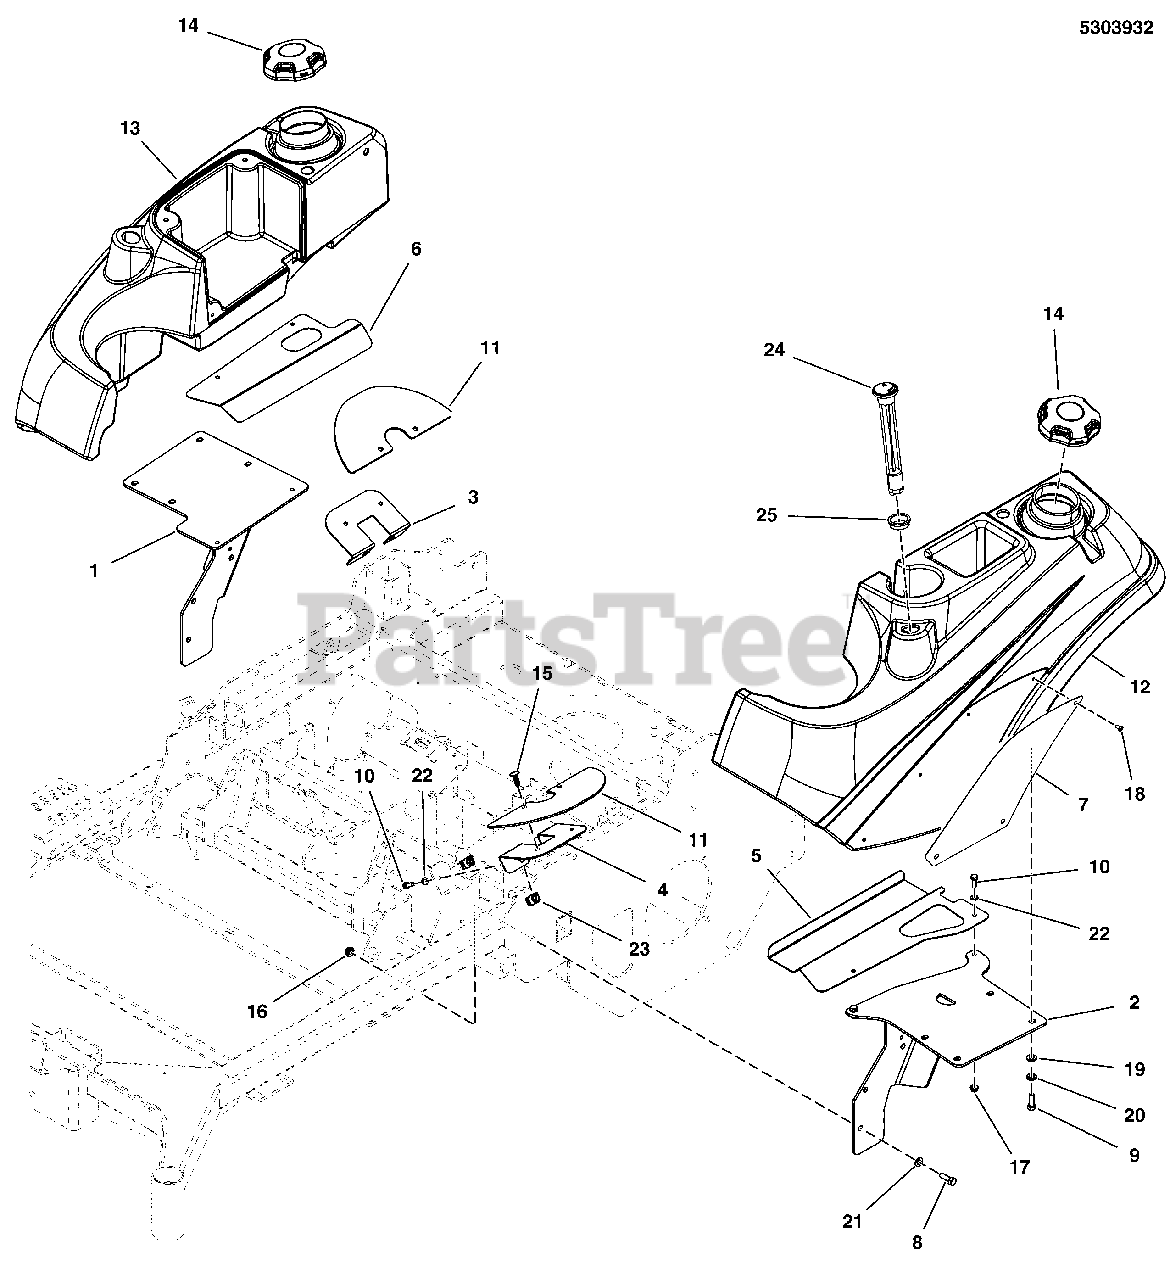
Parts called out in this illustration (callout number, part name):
1	WELD, FUEL MOUNT, RH, MASSEY 3900 - BLK
2	WELD, FUEL MOUNT, LH, MASSEY 3900 - BLK
3	GUARD,MOTION CONTROLS,RH,MASSEY 3900-BLK
4	GUARD,MOTION CONTROLS,LH,MASSEY 3900-BLK
5	GUARD, SEAT, LH - BLK
6	GUARD, SEAT, RH - BLK
7	PLATE, TANK BADGE - IS2000/COBALT - RED
8	BOLT, 5/16-18 X 1 GD5 CZ
9	BOLT, 5/16-18 X 3/4 GD5
10	BOLT, 1/4-20 X 3/4 GD5 CZ
11	GUARD, RUBBER MOTION CONTROL
12	TANK, FUEL, 5.75 GAL,MED, Z-LH, LOW PERM
13	TANK, FUEL, 5.25 GAL,MED, Z-RH, LOW PERM
14	FUEL CAP, 3-1/2", MANAGED VENT OUT, 12"
15	PUSH RIVET (TREE TYPE), BLACK
16	NUT, 5/16-18 HEX NYLOCK FLANGE
17	NUT, 1/4-20 HEX NYLOCK FLANGE
18	SCREW, #10-24 X 3/8 ALLEN BHBZ
19	WASHER, 5/16 F436 FLAT
20	WASHER, 5/16 LOCK CZ
21	WASHER, 5/16" SAE
22	WASHER, 1/4 SAE
23	BODY CLIP, 1/4-20 X 1/2 DEEP
24	FUEL GAUGE, 12" (SV)
25	GROMMET, FUEL GAUGE (SV)
